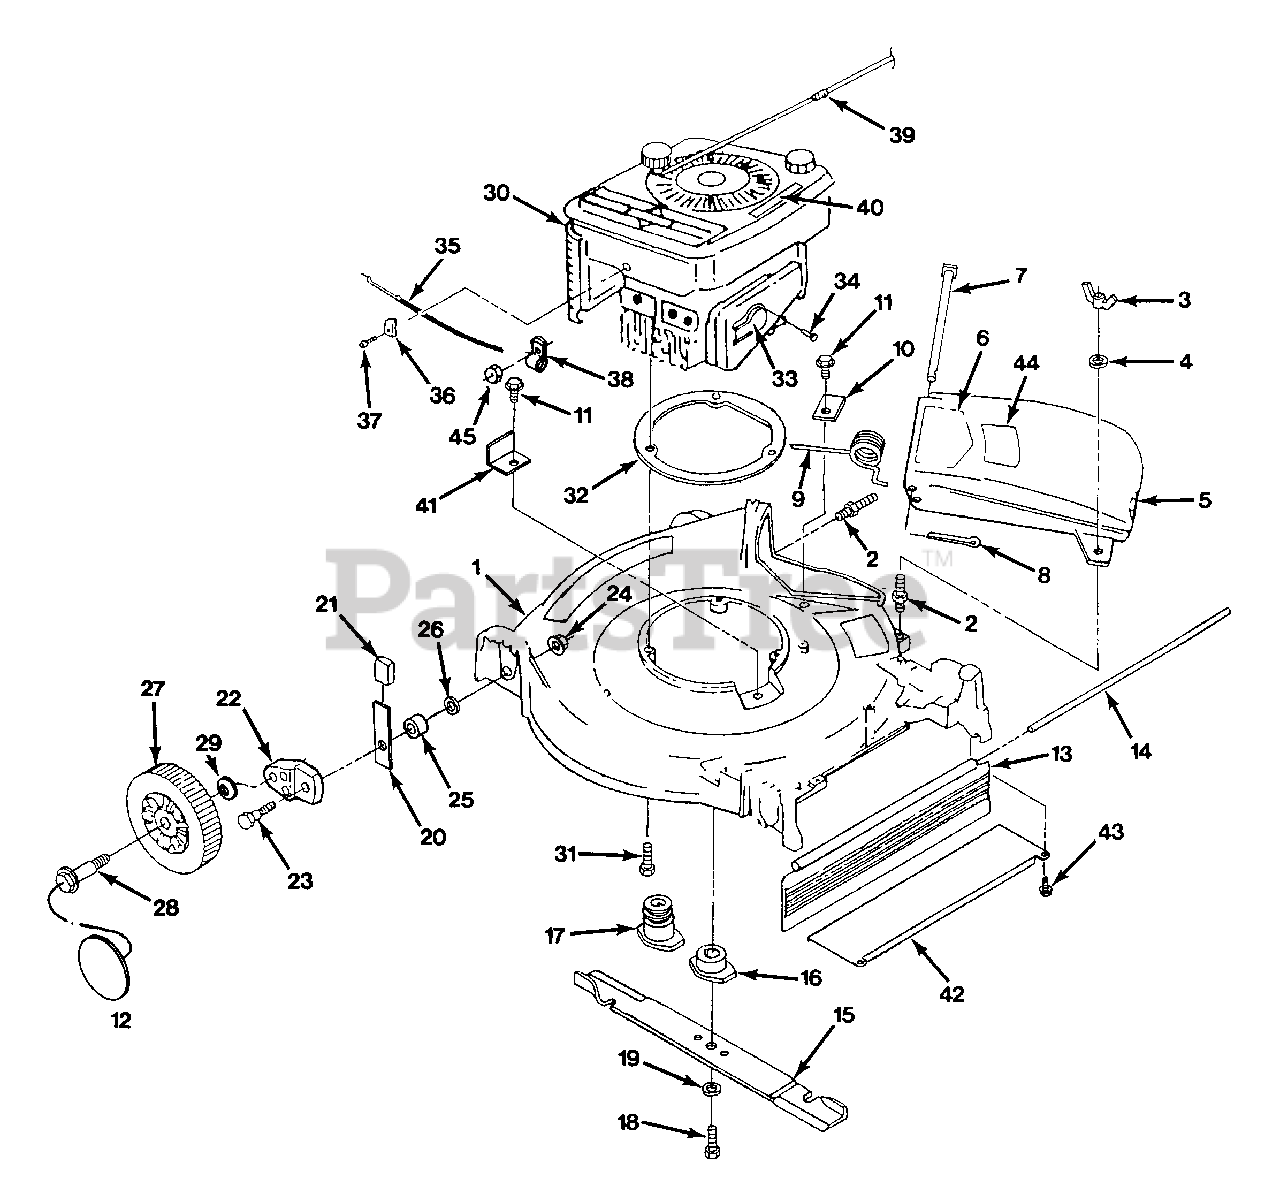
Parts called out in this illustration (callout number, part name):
1	Deck - 20" propelled
2	Stud - 1/4-20 x 3/4
3	Nut - wing 1/4-20 nylock
4	Washer - flat 1/4
5	Cover - discharge opening
6	Decal - DANGER CPSC
7	Pin - hinge
8	Pin - cotter
9	Spring - cover
10	Bracket - rear bagger
11	Screw - hex tap 1/4-20 x 1/2
13	Flap - drag
14	Rod - drag flap
15	Blade - cutter 20"
16	Adapter - blade
17	Adapter - blade w/pulley
18	Bolt - hex 3/8-24 x 1-1/4 Gde 8
19	Washer - split lock 3/8 hvy
20	Lever - height adjuster
21	Tip - adjuster lever
22	Arm - wheel mount
23	Bolt - hex 5/16-18 x 1-5/8 shldr
24	Nut - hex 5/16-18 flnge lock
25	Spacer - adjuster lever
26	Washer - flat 5/16
27	Wheel - 8"
28	Bolt - wheel 3/8-16
29	Washer - Belleville
30	Engine
31	Bolt - hex 3/8-16 x 1 1/2
32	Ring - engine
33	Deflector - muffler
34	Screw-tap #8-32 x 3/8
35	Control - throttle w/cable
36	Clamp - cable
37	Screw - tap #10-16 x 5/8
38	Clip - cable
39	Stop - rope
40	Decal - DANGER, blade moving
41	Cover - belt opening
42	Cover - rear
43	Screw - hex 1/4-20 x 3/4
44	Decal - DANGER
45	Nut - hex 1/4-20 lock
